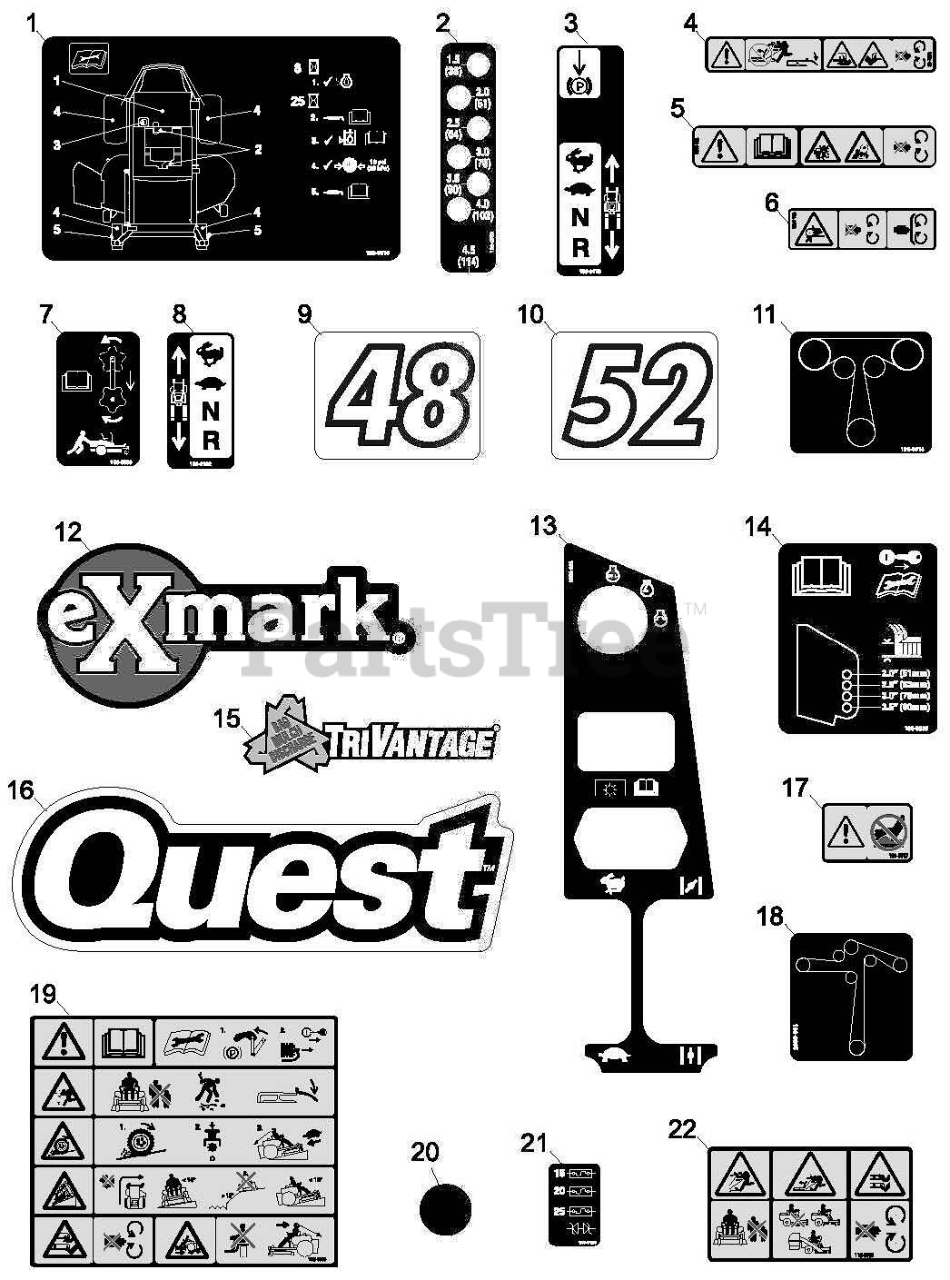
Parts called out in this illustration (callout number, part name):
1	DECAL-SERVICE AID
2	DECAL-CUT HEIGHT
3	DECAL-CONTROL BRAKE
4	DECAL-DANGER
5	DECAL-DANGER
6	DECAL-WARNING, BELT SHIEL
7	DECAL-DRIVE RELEASE
8	DECAL-MOTION CONTROL
9	DECAL,DECK 48
10	DECAL,DECK 52
11	DECAL-ROUTING, BELT
12	DECAL,EXMARK LOGO
13	DECAL-CONSOLE
14	DECAL-ROLLER, ANTI-SCALP
16	DECAL,QUEST LOGO
17	DECAL-WARNING
18	DECAL-ROUTING, BELT
19	DECAL-SAFETY
20	DECAL-HOLE COVER
21	DECAL-FUSE BLOCK
22	DECAL-DANGER
